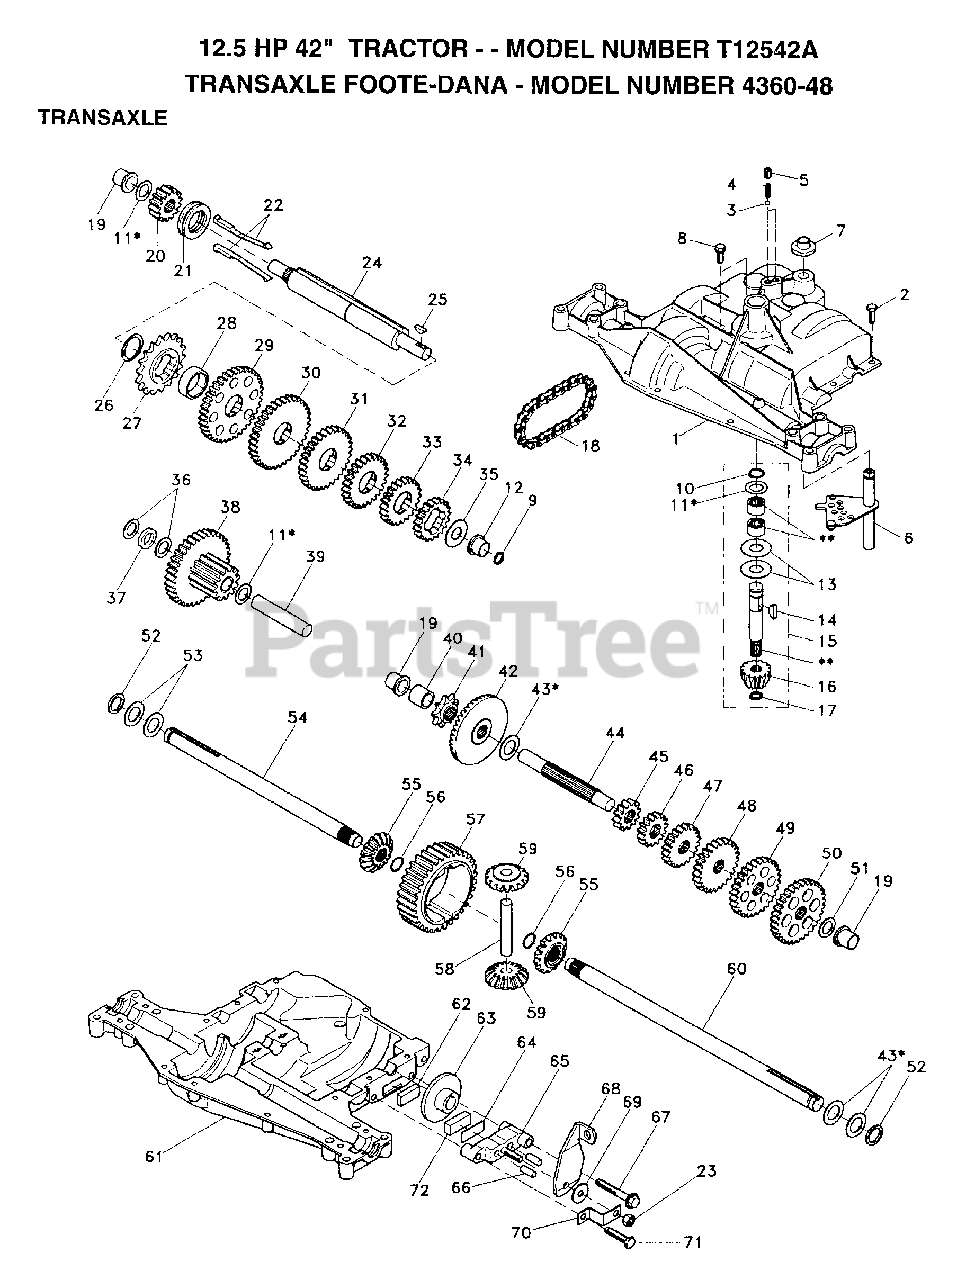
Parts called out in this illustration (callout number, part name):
4	"SPRING, DETENT LT"
5	"SCREW, SET LT"
6	KIT SHIFTER ASM
7	SHIFTER BOOT
8	SCREW TAP W/SEAL
9	SQUARE RING
10	RETAINING RING LT
11	ASM KIT SHIM 4689
12	"FLANGE, BEARING"
13	WASHER T
14	WOODRUFF KEY
15	AS KIT INPUT SHFT
16	PINION 14T T
17	"RING,RETAINING LT"
18	"CHAIN,24 PTCH LT"
19	BEARING.FLNG.5510
20	GEAR SPUR 14T
21	COLLAR CLUTCH
22	ASM KIT CLTCH KEY
23	NUT.LOCK.5/16-24
24	SHAFT INTERM
25	WOODRUFF KEY
26	"RING,RETAINING LT"
27	SPROCKET 18T T
28	SPACER YT
29	KIT.GEAR.12/37TH
32	GEAR 25T LT
33	GEAR SPUR 22 TT
34	SPUR GEAR 19T
35	"WASHER, PLAIN LT"
36	WASHER 025
37	SPACER
38	ASSM GEAR COMB
39	SHAFT IDLER
40	SPACER T
41	SPROCKET 9T LT
43	ASM KIT SHIM
44	SHAFT T
48	"GEAR, SPUR 25T LT"
49	GEAR 28T T
50	"GEAR, SPUR 31T LT"
51	WASHER 060
52	NEOPRENE WASHER
53	WASHER 031
55	GEAR 15T T
56	"RING,RETAINING LT"
58	SHAFT T
59	GEAR 1ST T
62	PUCK T
63	BRAKE DISC. T
64	SPACER LT
66	PIN T
69	WASHER LT
71	"SCREW, TAPPING LT"
72	PUCK T
